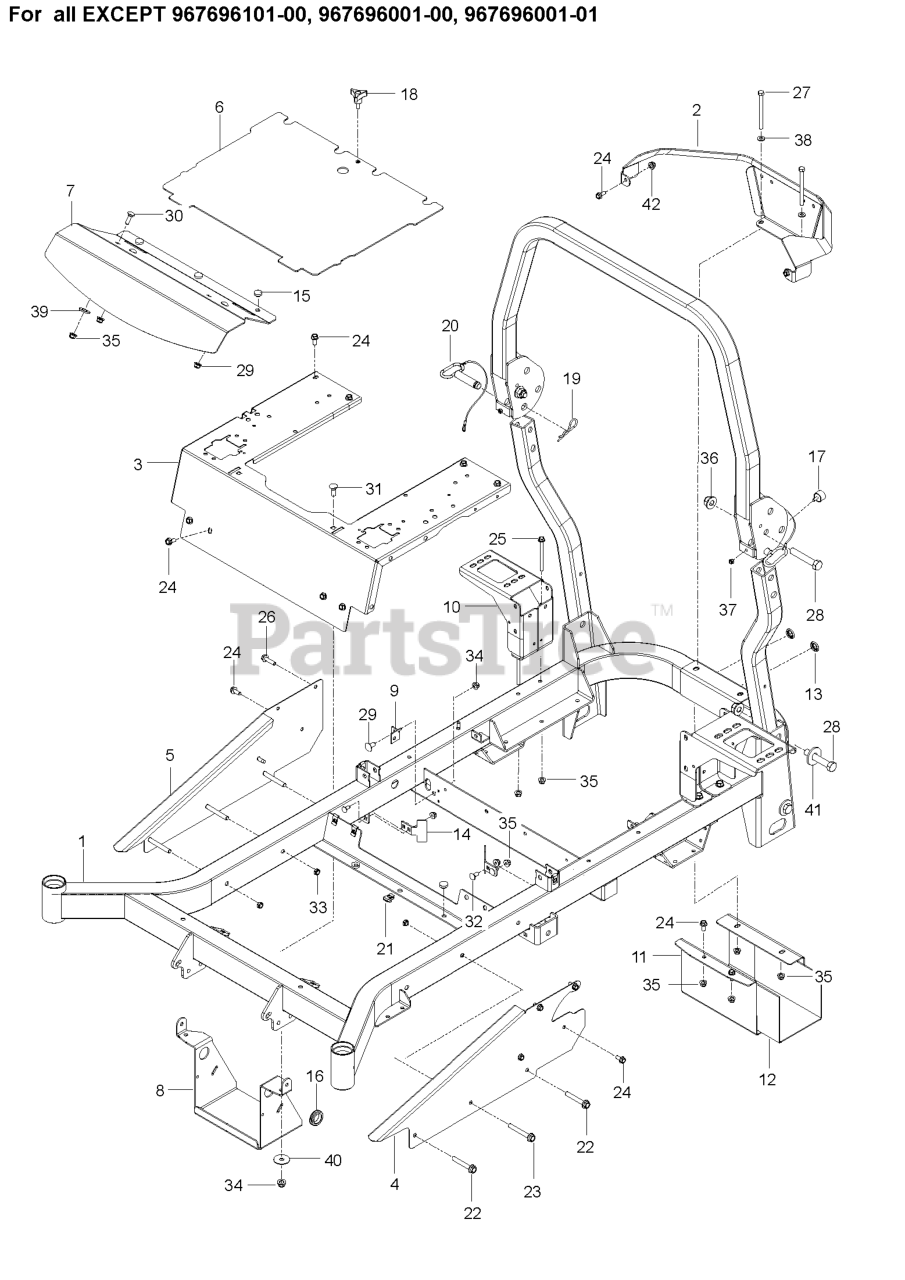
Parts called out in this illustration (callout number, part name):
1	KIT.FRAME.W/DECALS.X668
2	GUARD.PNT.REAR.MZ.GRAY
2	Guards
3	SUPPORT.PNT.SEAT.CONTROL.ORNG
3	SUPPORT SEAT CONTROL ORANGE X6
4	SIDE.LT.ORANGE
5	SIDE.RT.ORANGE
6	PLATE FLOOR ORANGE
6	PLATE, FLOOR W/DECALS
7	PLATE FOOTREST ORANBE MS668
7	PLATE, FOOTREST
8	BRACKET BATTERY BLACK MS-431
8	BRACKET.PNT.BATTERY.BLK
9	BRACKET.DAMPENER.BLACK
10	MOUNT, TANK, ZT BLK
11	SHIELD.MUFFLER.BLACK
12	HEAT SHIELD
13	CAP.PLUG.BP-1.BLACK
14	STOP, DECK, EZ+
15	GROMMET, BUMPER
16	RUBBER GROMMET
17	BUMPER, MALE STUD, 1/4-20
17	U-CLIP 5/16-18 NUT RETAINER
18	KNOB W/STUD
18	GSPW Knobs
19	Pins
19	PIN HAIR .148 X 2-15/16 #210
19	WASHER
20	PIN, ROPS
20	WASHER 1/2" FLAT
21	U-CLIP 5/16-18 NUT RETAINER
21	WASHER.13/32X1-1/2X16GA
22	HHFS 3/8-16 X 2.5 GR 5 ZD
23	HHFS 3/8-16 X 2-3/4 GR5 ZD
24	HHFS 5/16-18 X 3/4
24	Bolts
25	BOLT.HEX.FLNG.5/16-18X3.75
26	HHFS 5/16-18 X 1.25 TPBLT GD 5
27	Bolts
27	HCS 5/16C X 4
28	BOLT 5/16C X 3/4" CARRIAGE
28	5/8-11 X 3-1/2 HHB GRADE 5
28	Bolts
29	BOLT
29	Bolts
29	GSPW Bolts
30	Bolts
30	RHSNB 5/16C X 1
31	RHSNB 3/8C X 1
32	5/16-18 NYLOC FLANGE NUT
32	BOLT 5/16C X 3/4" CARRIAGE
33	NUT HEX 3/8-16 NYLON, THIN
34	NUT 3/8-16 HEX FLG NYLOC ZD
35	5/16-18 NYLOC FLANGE NUT
35	NUT HEXAGON FLANGE 5/16-18 ST
36	Nuts
36	NUT 5/8-11 FLG NYLOC ZD
37	NUT.1/4-20.HEX.NYLOC.ZD
37	NUT HEXAGON 1/4-20 ST ZPB
38	Bolts
38	WASHER
39	WASHER 1/2" FLAT
39	Washers
40	WASHER.13/32X1-1/2X16GA
41	WASHER, 5/8 FLAT
41	Washers
42	NUT HEXAGON FLANGE 5/16-18 ST
